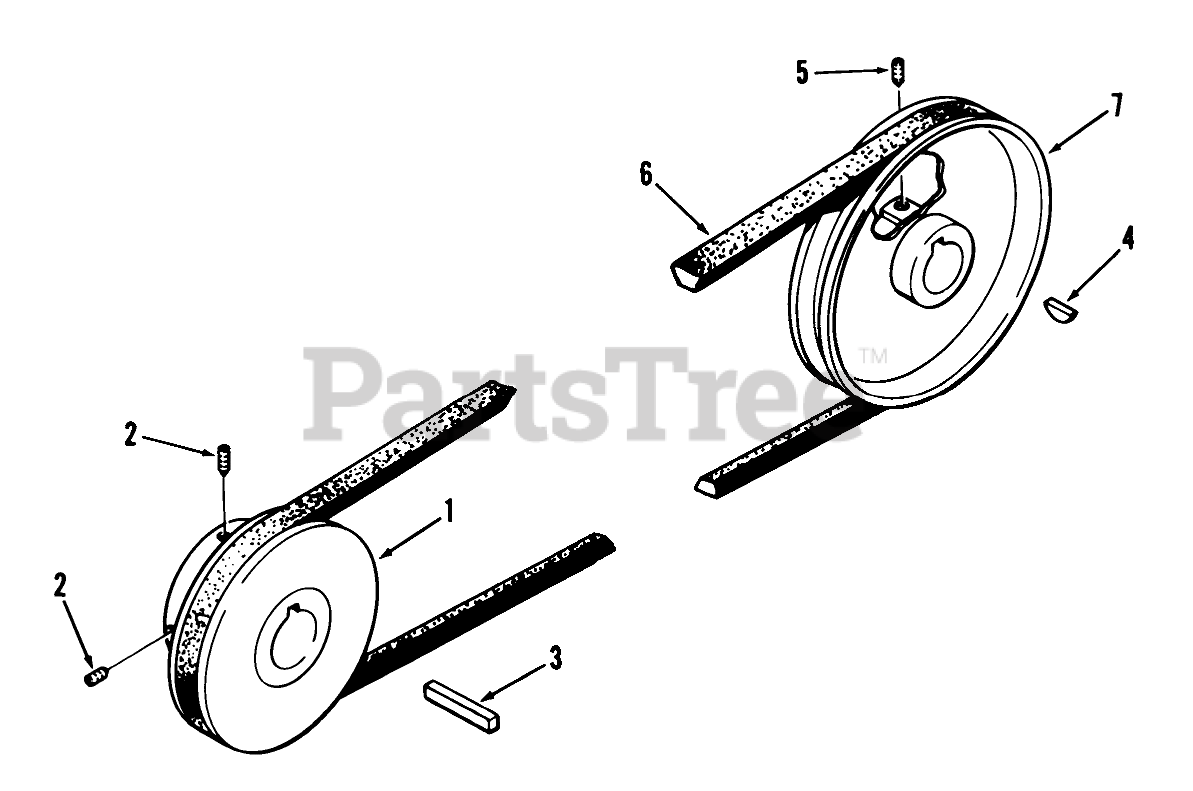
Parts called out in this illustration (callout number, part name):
1	PULLEY
3	KEY-STRAIGHT
4	KEY-HI PRO
5	Set Screw 5/16-18 X 5/8
6	Drive Belt
7	PULLEY-TRANSMISSION
